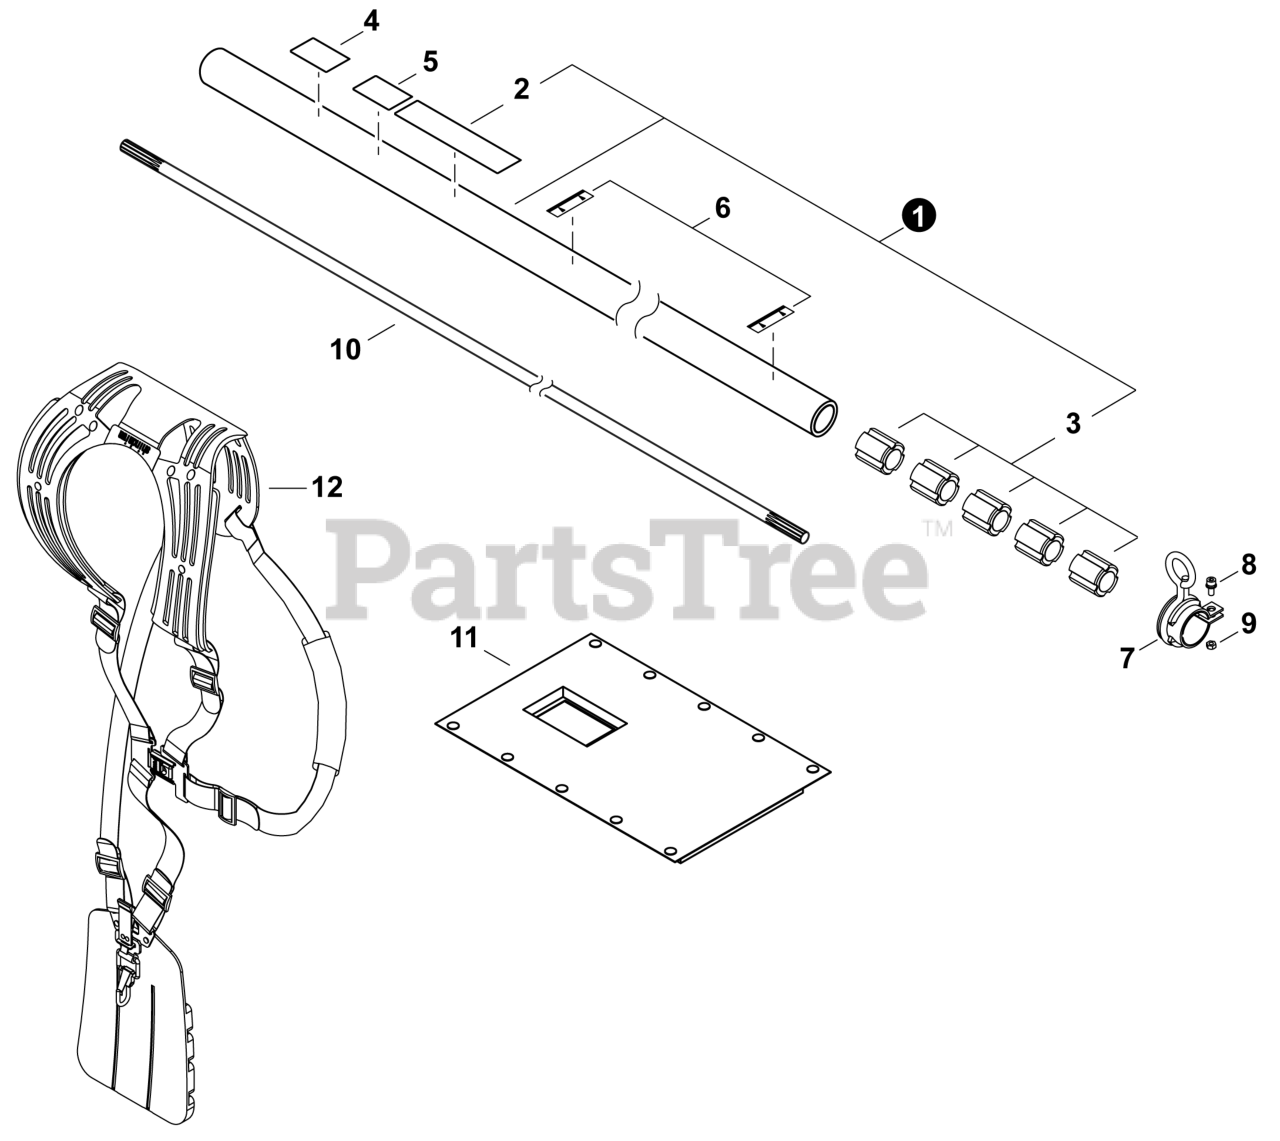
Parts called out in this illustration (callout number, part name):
1	MAIN PIPE ASSY
2	LABEL - CAUTION
3	BUSHING
4	LABEL - SPEED
5	LABEL - NOISE
6	LABEL - ALIGNMENT
8	BOLT 5x14
10	DRIVESHAFT
11	PROTECTOR
12	HARNESS ASSY
